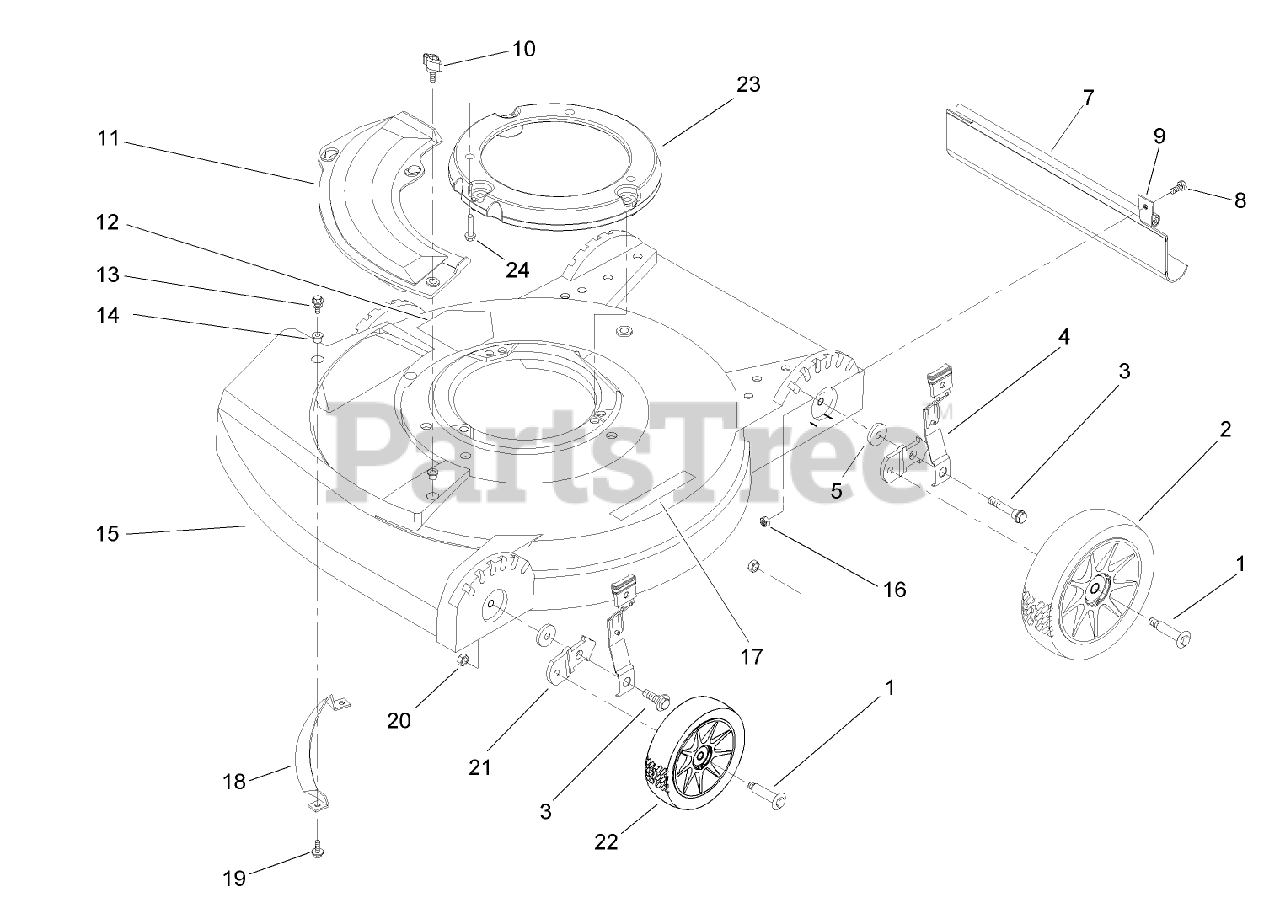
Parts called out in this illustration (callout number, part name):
2	WHEEL/TIRE ASM
4	SPRING ARM ASM
5	WASHER
7	SHIELD-TRAILING
8	SCREW-HH
9	CLAMP-SHIELD
11	PLATE-OPENING, CHUTE
12	DECAL-DANGER
13	SCREW-SEMS
14	NUT-CLIP
15	HOUSING ASM
16	NUT-LOCK, NI
17	DECAL-WARNING
18	BAR-TOE
19	SCREW-HWH
20	NUT-LOCK, NI
21	BRACKET-HEIGHT, WHEEL
22	WHEEL AND TIRE ASM
23	SPACER-ENGINE
24	SCREW-MOUNT, ENGINE
